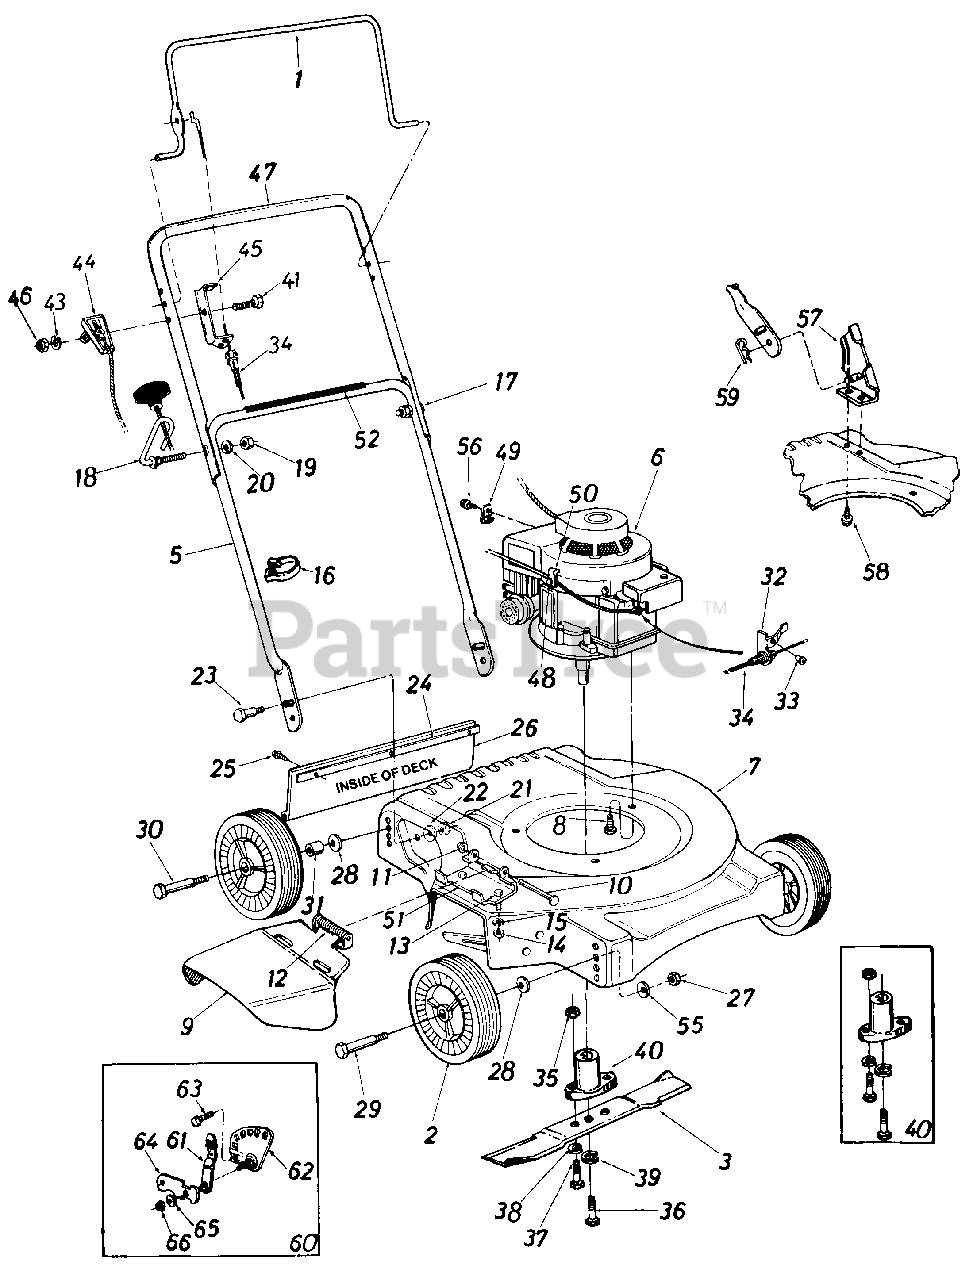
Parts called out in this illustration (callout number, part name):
1	Control Handle-R.H.
2	Plastic Wheel Ass'y.
3	22" Blade
5	Lower Handle (Painted)
6	Engine
8	Hex Wash. Hd. TT-Tap Scr. 3/8-16 x 1.00" Lg.
9	Chute Deflector Ass'y.
10	Pivot Pin
11	Cap Speed Nut 1/4" Rod
12	Torsion Spring
13	Hex Bolt 1/4-20 x .50" Lg.*
14	Hex Nut 1/4-20 Thd.*
15	L-Wash. 1/4" I.D.*
16	Cable Tie
17	Curved Carriage Bolt 5/16-18 x 1.38" Lg.
18	Rope Guide Bolt
19	Hex Nut 5/16-18 Thd.*
20	L-Wash. 5/16" I.D.*
21	Hex Ins. L-Nut 5/16-18 Thd.
22	Bell-Wash. .345" I.D. x .88" O.D.
23	Shld. Bolt .437" Dia. x .268" Lg.
24	Retainer Strip
25	Hex Wash. Hd. Self-Tap Scr. 1/4 x.62" Lg.
26	Rear Flap Ass'y.
27	Hex Nut 3/8-16 Thd.*
28	Bell-Wash. .400" I.D. x .88"
29	Axle Bolt
30	Axle Bolt
31	Spacer
32	Cable Bracket
33	Pop Rivet .156" Dia. x .379
34	Control Cable-43"
35	Hex Nut 5/16-24 Thd.*
36	Hex Bolt 3/8-24 x 1.00" Lg. (Grade 5)
37	Hex Bolt 5/16-24 x 1.00" Lg. (Grade 5)
38	L-Wash. 5/16" I.D.*
39	L-Wash. 3/8" I.D. Heavy Duty
40	Blade Adapter Kit
41	Hex Bolt 1/4-28 x 1.75" Lg.*
43	L-Wash. 1/4" I.D.
44	Throttle Control Ass'y.-Comp.
45	Cable Mounting Brkt.
46	Hex Nut 1/4-28 Thd.
47	Upper Handle (Painted)
48	Hex B-Tap Scr. #10 x .38" Lg.
49	Casing Clamp
50	Casing Clamp
51	Hinge Plate
52	Instruction Label-Handle
55	Bell-Wash. .39" I.D. x 1.13" O.D.
56	Hex AB-Tap Scr. #8 x .38"
57	Handle Mount Brkt. Ass'y.-L.H.
58	Hex Self-Tap Scr. 5/16-18 x .50" Lg.
59	Hairpin Cotter
60	Height Adj. Ass'y. Comp.-L.H.
61	Spring Lever w/Knob
63	Hex Sems Bolt 3/8-16 x .62" Lg.
64	Pivot Bar
65	Bell-Wash. .40" I.D. x 1.13" O.D.
66	Elastic Stop Nut
